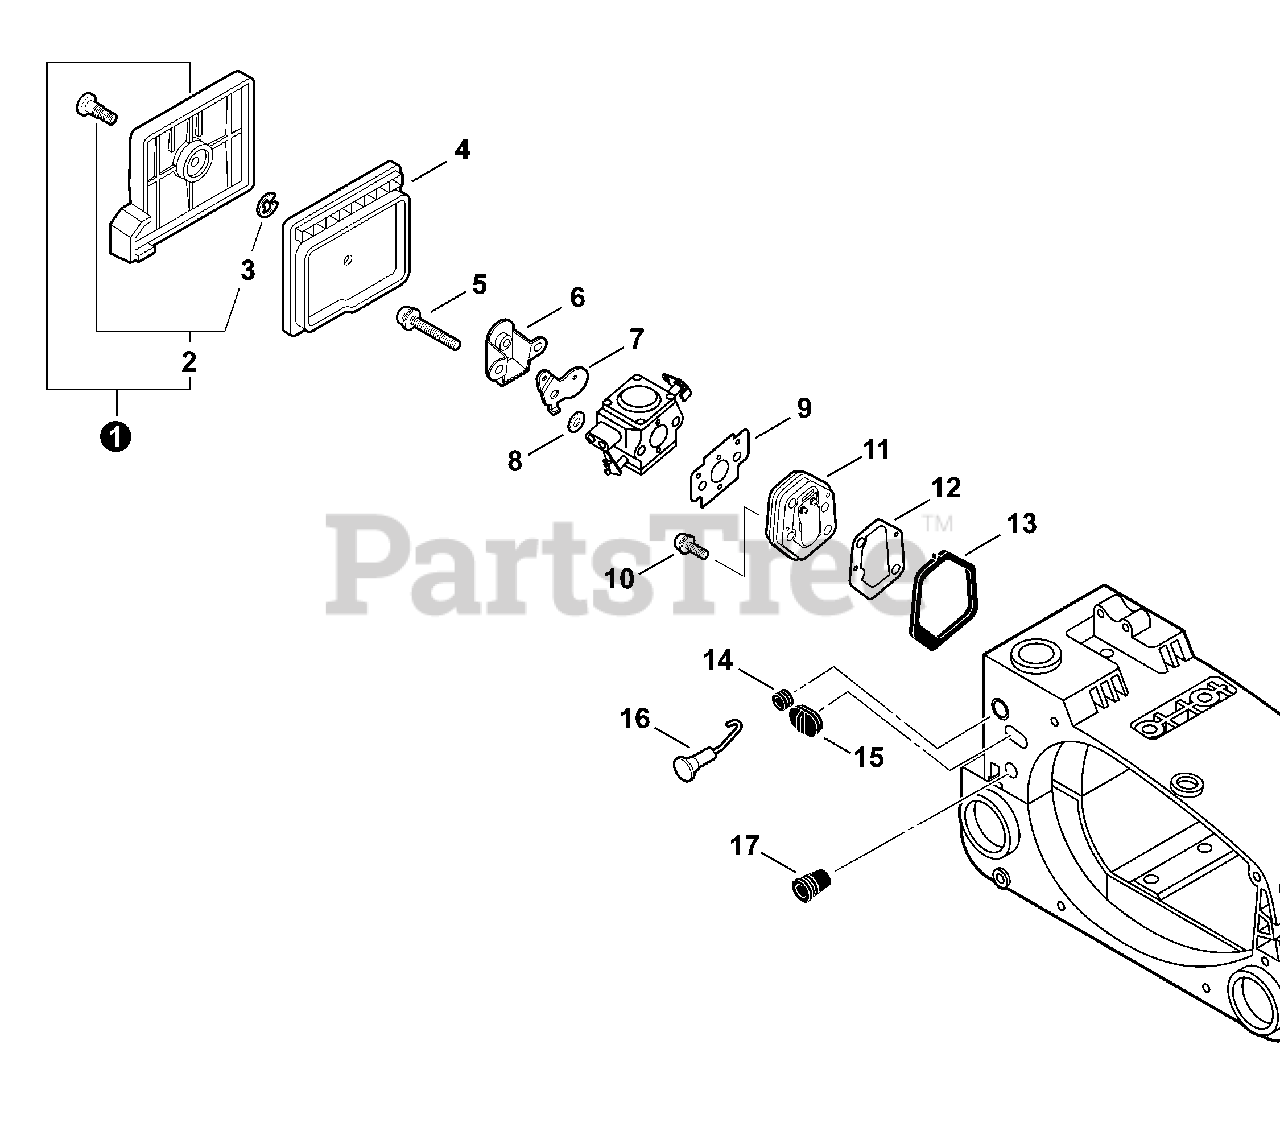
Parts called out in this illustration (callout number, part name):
1	COVER ASSY, AIR FILTER
2	THUMBSCREW
3	E-RING 4
4	FILTER, AIR
5	SCREW 5×45
6	PLATE, PREVENT
7	SHUTTER, CHOKE
8	WASHER 5.2×8×0.8T
9	GASKET, INTAKE
10	SCREW 5×18
11	INSULATOR KIT
12	GASKET, INTAKE
13	SEAL, INTAKE
14	GROMMET, CHOKE
15	GROMMET, NEEDLE
16	ROD, CHOKE
17	GROMMET, IDLE
